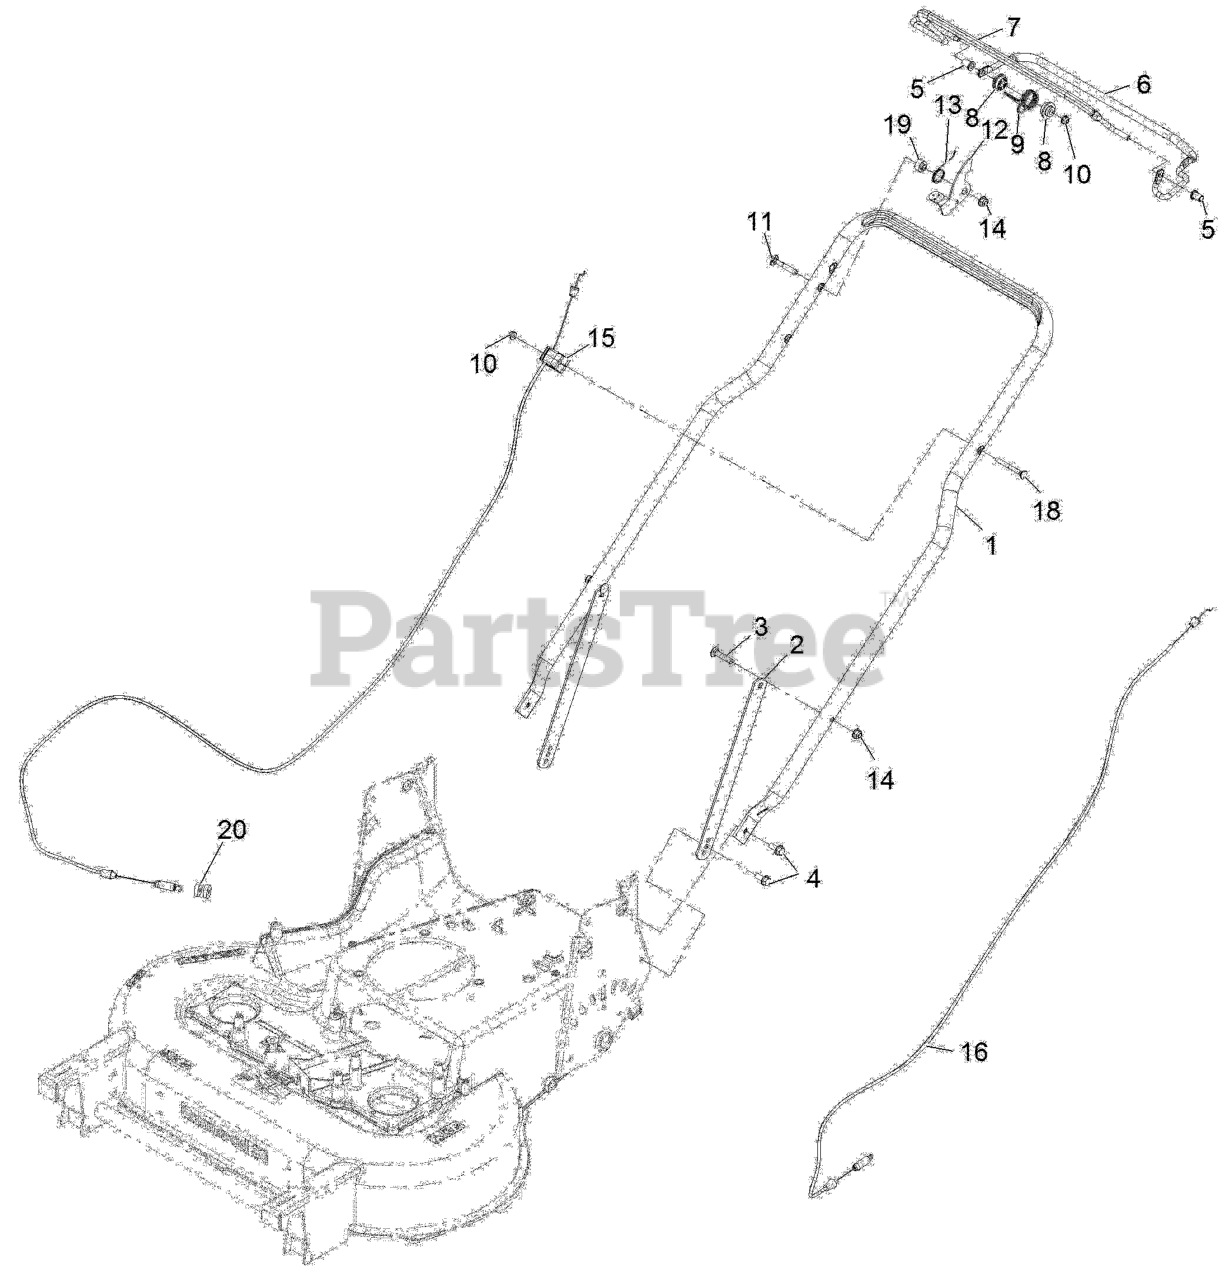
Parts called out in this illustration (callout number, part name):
2	SUPPORT-HANDLE
3	BOLT-CARR
4	SCREW-HHF
5	BUSHING-HANDLEBAR
6	BAIL-DRIVE COATED
8	BUSHING-SPRING, PIVOT
9	SPRING-RETURN, BBC
12	LEVER-BBC
13	SPRING-LEVER, BBC
14	NUT-HF, NI
16	CABLE-TRACTION
18	SCREW-HANDLE
19	BUSHING-STEPPED
